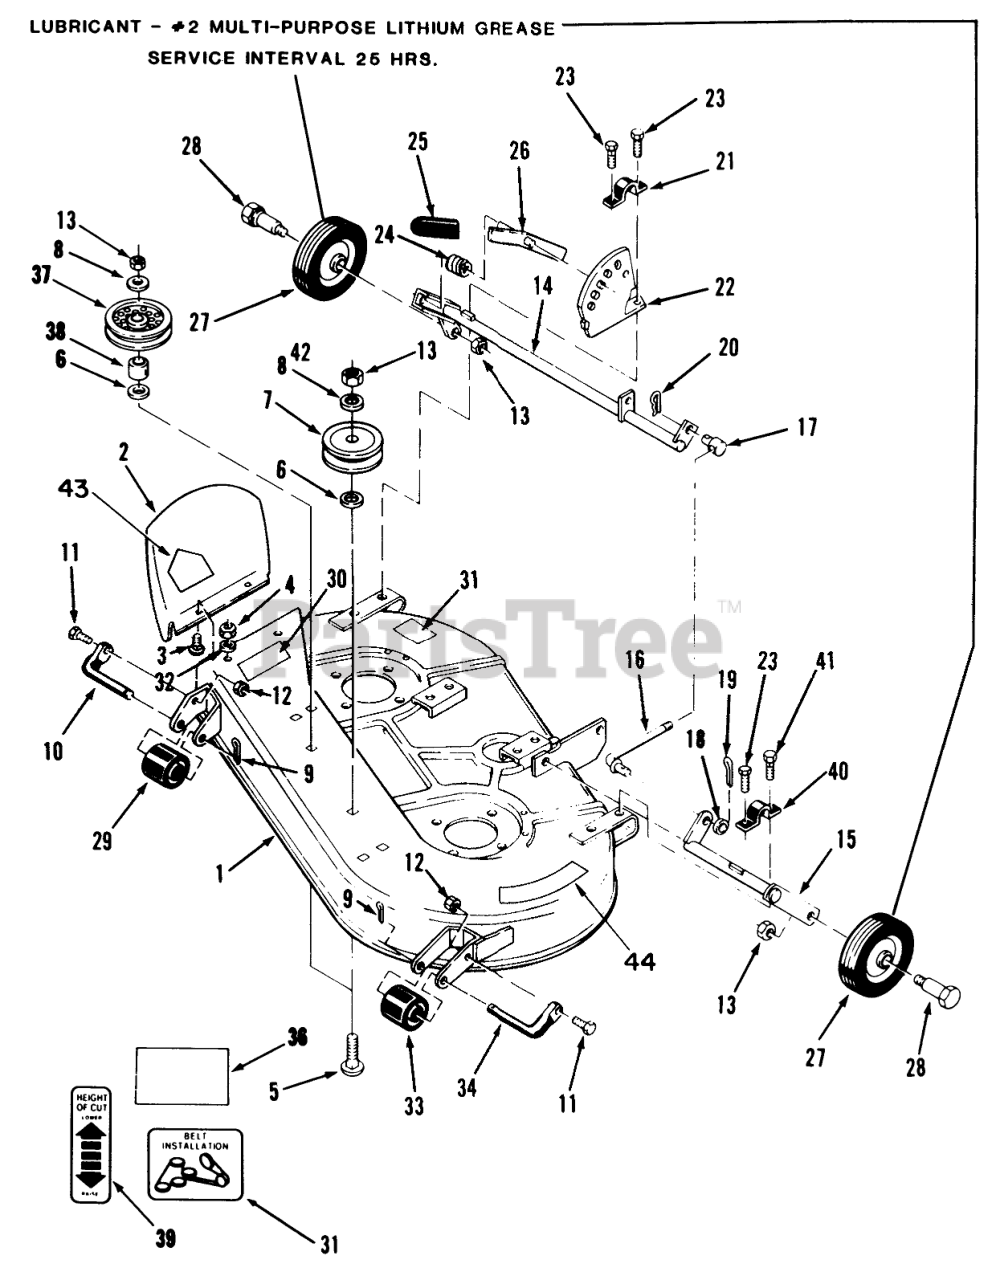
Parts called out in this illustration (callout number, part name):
1	Deck-Mower
2	Chute Extension
3	Bolt
4	Nut
5	Bolt
6	WASHER-FLAT
7	PULLEY-IDLER
8	WASHER
9	Cotter Pin
10	ROLLER-SHAFT
11	Bolt
12	Nut
13	NUT
14	Gage Wheel Support RH
15	WA GAG WHL R
16	ROD CONNECTING
17	TRUNNION
18	Washer
19	Pop Rivet
20	Hairpin
22	Quadrant
23	Bolt
24	SPRING-COMPRESSION
26	Lever
27	WHEEL
28	BOLT-SHOULDER
29	Roller
30	DECAL-DANGER, THROWN OBJECT
31	DECAL BELT INSTALLAT
32	WASHER 5/16 SAE
33	ROLLER
34	SHAFT-ROLLER
36	DECAL-OVERLAY
37	PULLEY-FLAT IDLER B
38	SPACER
39	DECAL-HOC
40	CLAMP B
41	Bolt
42	Washer
43	DECAL-DANGER
44	DECAL - DANGER
